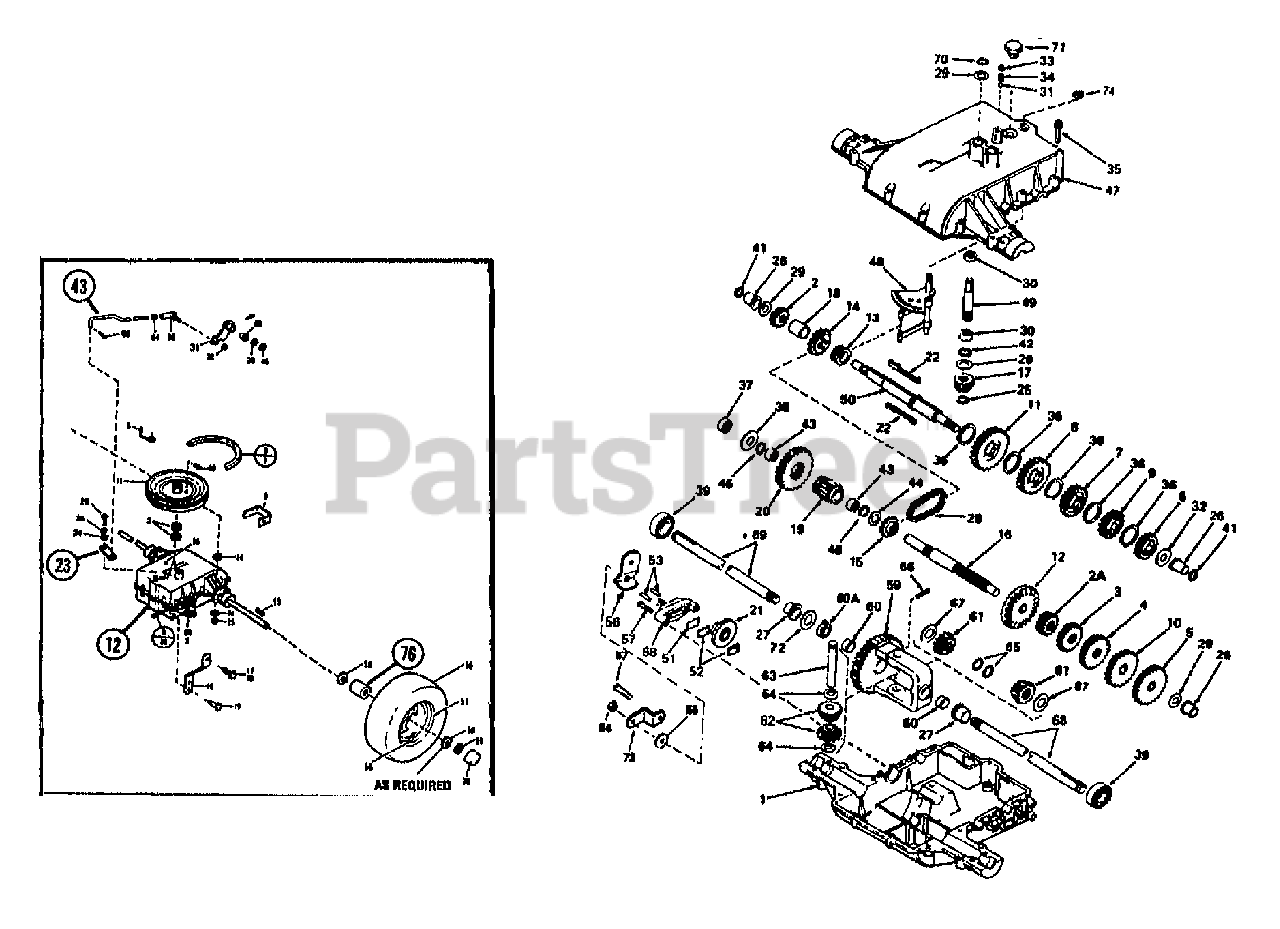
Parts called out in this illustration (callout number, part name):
1	TRANSAXLE CASE
2	SPUR GEAR
2A	SPUR GEAR
3	SPUR GEAR
4	SPUR GEAR
5	SPUR GEAR
6	SPUR GEAR
7	SPUR GEAR
9	SPUR GEAR
10	SPUR GEAR
11	SPUR GEAR
12	5-SPEED TRANSMISSION
12	BEVEL GEAR
14	SPROCKET
15	SPROCKET
16	COUNTERSHAFT
17	INPUT PINION
19	OUTPUT GEAR
20	OUTPUT GEAR
21	BRAKE DISK
22	SHIFT KEY
25	RET RING
26	BUSHING
29	WASHER
30	NEEDLE BEARING
34	SPRING
36	WASHER
37	BALL BEARING
39	BALL BEARING
41	SQUARE CUT RING
43	ROD-SHIFT
43	NEEDLE BEARING
46	SQUARE CUT RING
49	INPUT SHAFT
50	BRAKE SHAFT
51	BRAKE PAD PLATE
52	BRAKE PAD
53	DOWEL PIN
56	BRAKE LEVER
59	DIFF GEAR ASSY
61	BEVEL GEAR
62	BEVEL GEAR
63	DRIVE PIN
65	RET RING
70	RET RING
